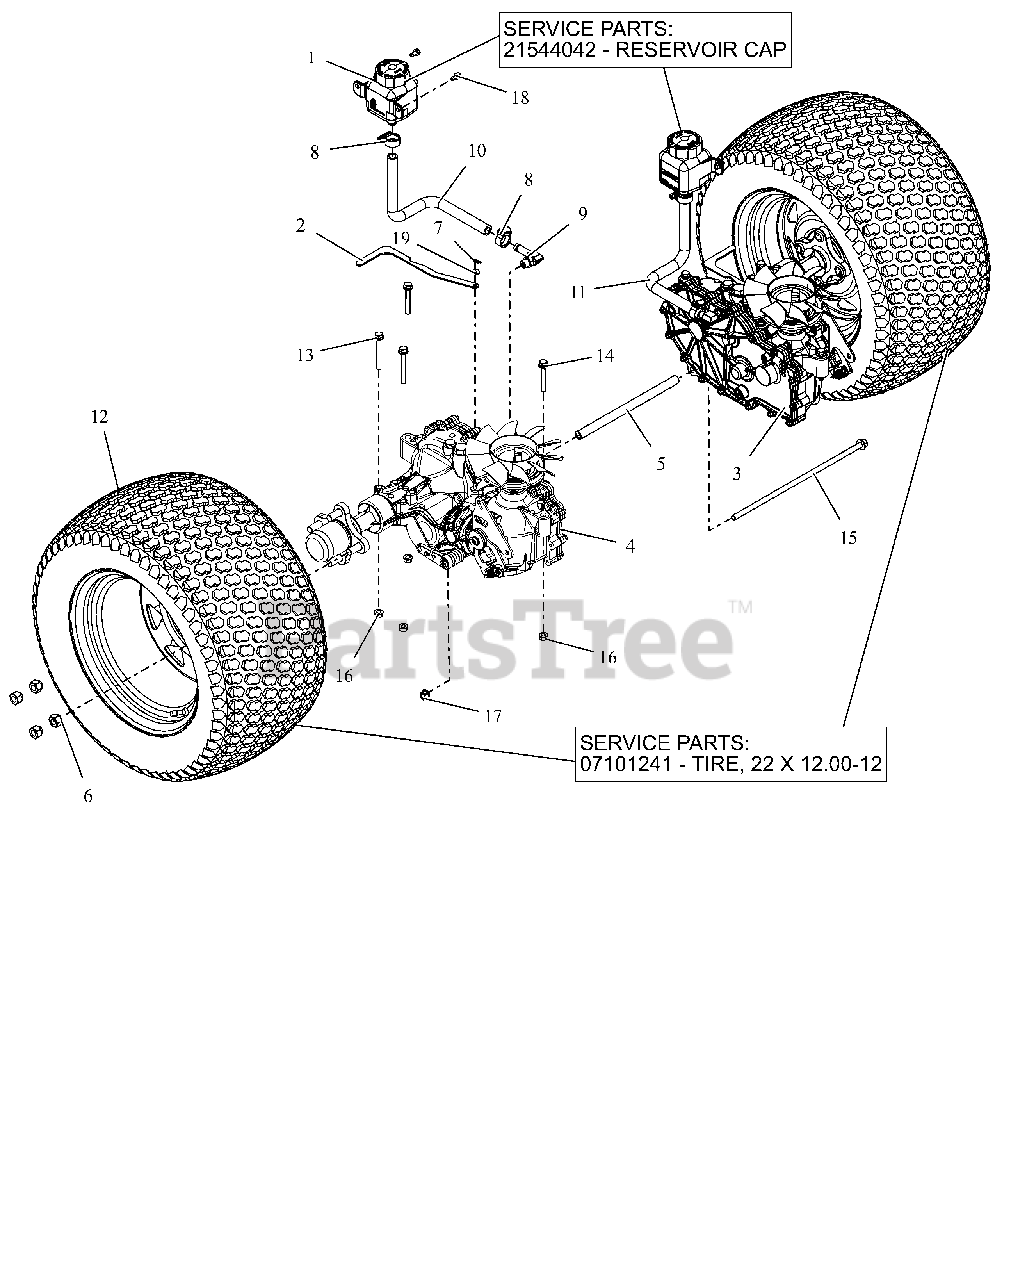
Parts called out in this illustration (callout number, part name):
1	TANK, EXPANSION
1	CAP, HYDRO RESERVOIR REPLAC.
2	BRKT, VALVE DUM
3	TRANSAXLE, ZT3200 LH
4	TRANSAXLE, RH ZT3200
5	SPCR, TRANSAXLE .406 ID X .630 OD X 9.95LG (BLACK)
6	NUT, WHEEL .50-20 ZCC
7	PIN, HAIR #225 .072X1.09
8	CLAMP,.88 DIA. HOSE
9	FITTING, HYD (90 DEG)
10	HOSE, FORMED EXPANSION -HD RH
11	HOSE, FORMED EXPANSION -HD LH
12	ASM, WHL/TIRE 22X12.00-12 K500
12	TIRE, 22X12.00-12
13	BLT,HEX-FLG .31-18X2.75 G5 ZCC
14	BLT,HEX-FLG .31-18X2.25 G5 ZCC
15	BLT, HEX-FLG 0.375-16X13 GR5 ZC120
16	NUT,LK-CTR-FLG .31-18 GF ZCC
17	NUT-LK-CTR-FLG .375-16 GF ZCC
18	SCR-TAP .25-20X.50 HWH ZCC
19	WSHR,FLT .281X.625X.065 ZCC
